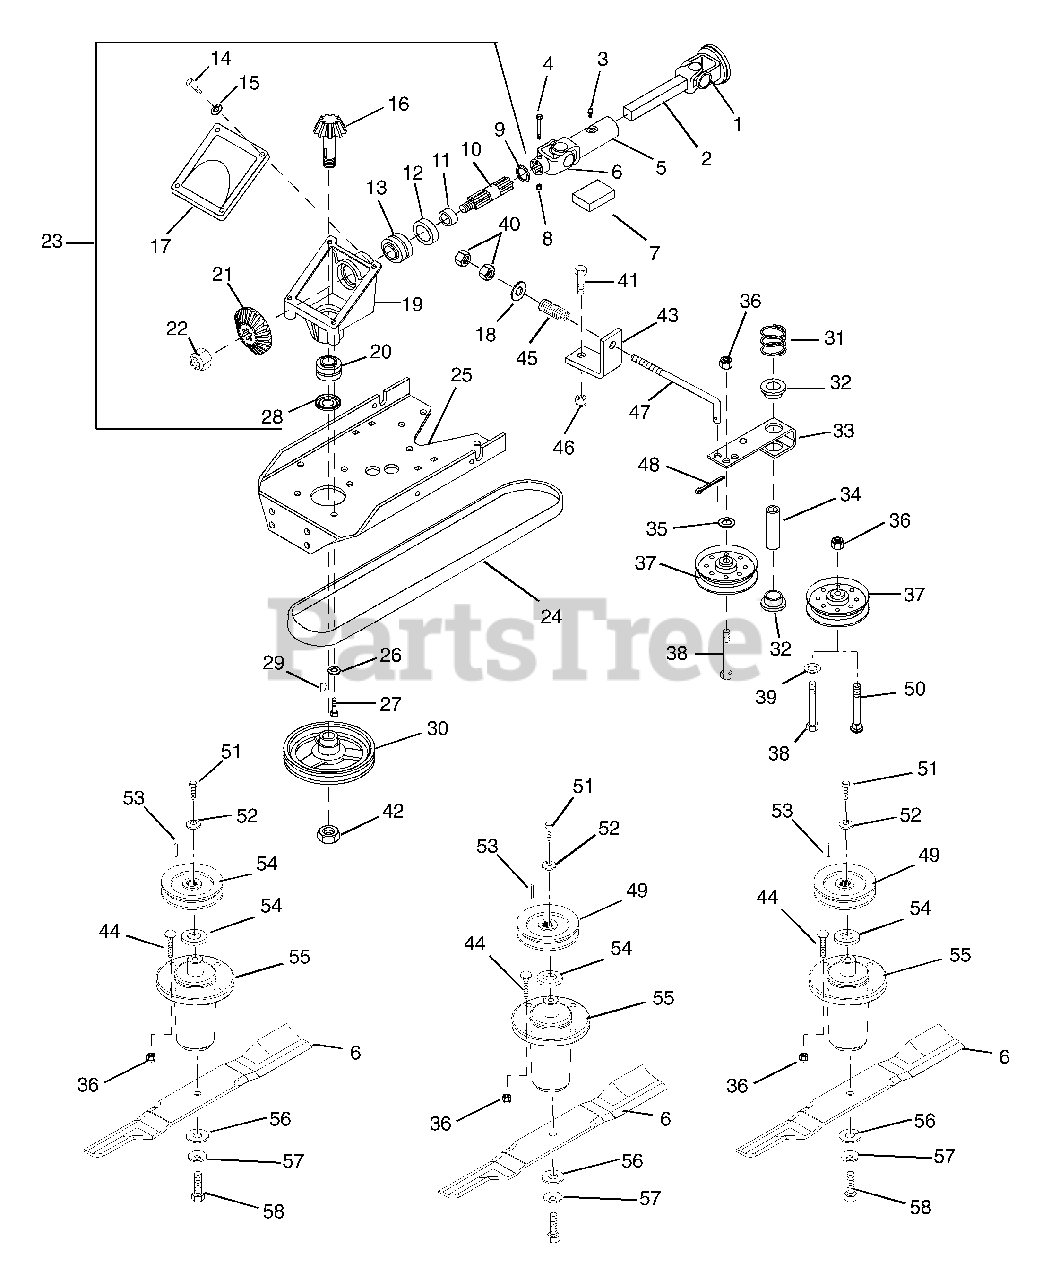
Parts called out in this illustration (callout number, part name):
1	Q. D. Yoke
2	Shaft,Propelled Square Bar
3	Fitting-Lube .25-28 x .256
4	Bolt-Hex .25-20 x 2.00 Grade 5
5	Joint-U Female End
6	Mower Blade Tungsten Carbide
7	Kit-Repair U-Joint
8	Nut-Locking-Nylon .25-20
9	Ring-Retaining 1.106 x .95
10	Shaft
11	Bushing Flange 1.00 x 1.25 x 1.25
12	Seal 1.250 x 1.983 x .250
13	Bearing-Assembly 1.000 x 1.980 x 1.243
14	Bolt-Hex .25-20 x .50 Grade 5
15	Washer-Locking .25 x .062 Regular
16	Shaft-Pinion Gear
17	Cover-Gear Housing
18	Washer-Flat-Steel .406 x .812 x .065
19	Casting-Gear Box
20	Bearing-Assembly .75 x 1.781 x 1.499
21	Gear-Bevel
22	Nut-Locking-Nylon .75-10
23	Assembly-Gearbox
24	V-Belt, Centermount
25	Support-Gear Housing
26	Washer-Locking .50 x .125
27	Bolt-Hex .50-13 x 1.00 Grade 5
28	Seal 1.250 x 1.691 x .310
29	Key-Woodruff .19 x .63
30	Sheave,Drive
31	Spring-Compression .085 x .80 x 1.00
32	Bushing-Flange .762 x 1.0 x .580 x 1.48
33	Arm-Idler Pivot
34	Spacer .560 x .750 x 2.437 Steel
35	Bushing .406 x .750 x .188
36	Nut-Locking-Nylon .38-16
37	Pulley-Idler 4.50 x .380
38	Bolt-Hex .38-16 x 2.00 Grade 5
39	Washer-Flat-Steel .438 x 1.00 x .083
40	Nut-Hex .375-24 Grade 2
41	Bolt-Hex .50-13 x 1.50
41	Bolt-Hex .50-13 x 1.375
42	Nut-Hex-Jam .75-10
43	Support-Spring
44	Bolt-Round Head Square Neck .38-16 x 1.25 Grade 5
45	Spring-Compression .125 x .78 x 1.00
46	Nut-Locking-Nylon .50-13
47	Rod, Idler 50 In. Mower
47	Rod, Idler 40 In. Mower
48	Pin-Cotter .09 x 1.00
49	Sheave, Spindle
50	Bolt-Round Head Square Neck .38-16X1.75 Grade 5
51	Bolt-Hex .38-16 x 1.00 Grade 8 with Epoxy Patch
52	Washer, Cupped, Serrated .375
53	Key-Square .25X1.00X.25 SAE 860 OR SAE 1035
54	Slinger, Dust
55	Maintenance Free Spindle Assembly
56	Washer, Flat .64 x 1.81 x .25
57	Washer-Bellville .63 x 1.63 x .14
58	Bolt, Blade
